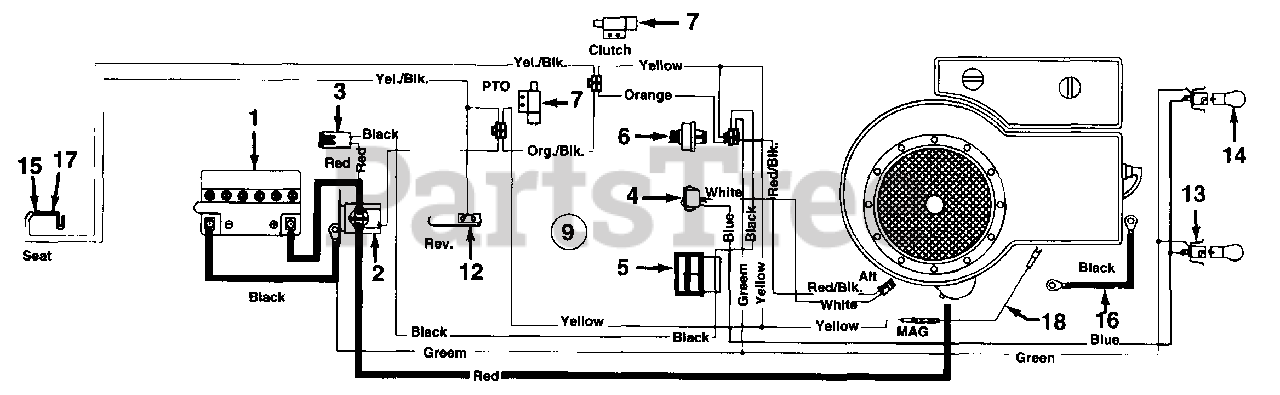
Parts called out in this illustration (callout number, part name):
1	Battery
2	Solenoid
3	Fuse 7.5 Amps
4	Light Switch
5	Ammeter
6	Ignition Switch
7	Safety Switch (Clutch)
9	Wire Harness w/o Ammeter
12	Safety Switch (Reverse)
13	Socket
14	Bulb (Headlight)
15	Safety Switch (Seat)
16	Ground Wire 7.5" Lg.
17	Safety Switch (Seat)
18	Harness Adaptor
